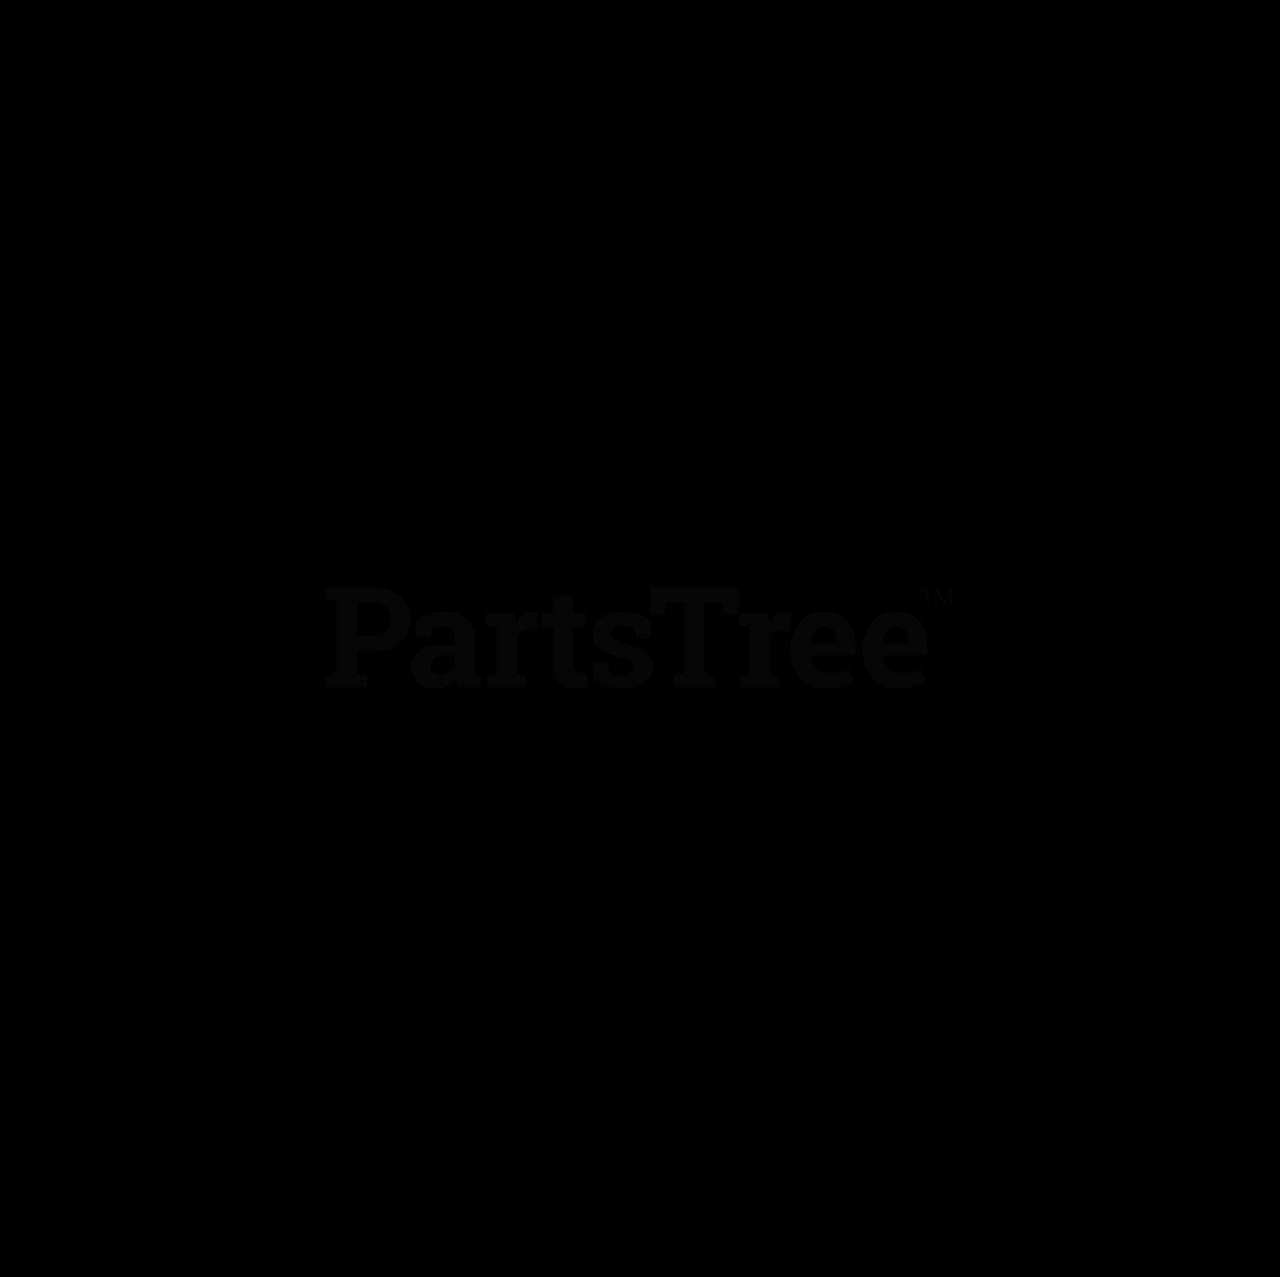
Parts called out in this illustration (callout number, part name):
1	ROPS, PT100 Replacement
2	Bolt, Hex .50-13 x 3.50
3	Assembly, ROPS Pin/Lanyard
4	Nut, Locking-Top-Flange .50-13
5	Bumper, ROPS Rubber
6	Bracket, ROPS Stop, Pro-TURN
7	Bolt, Hex .50-13 x 3.00
